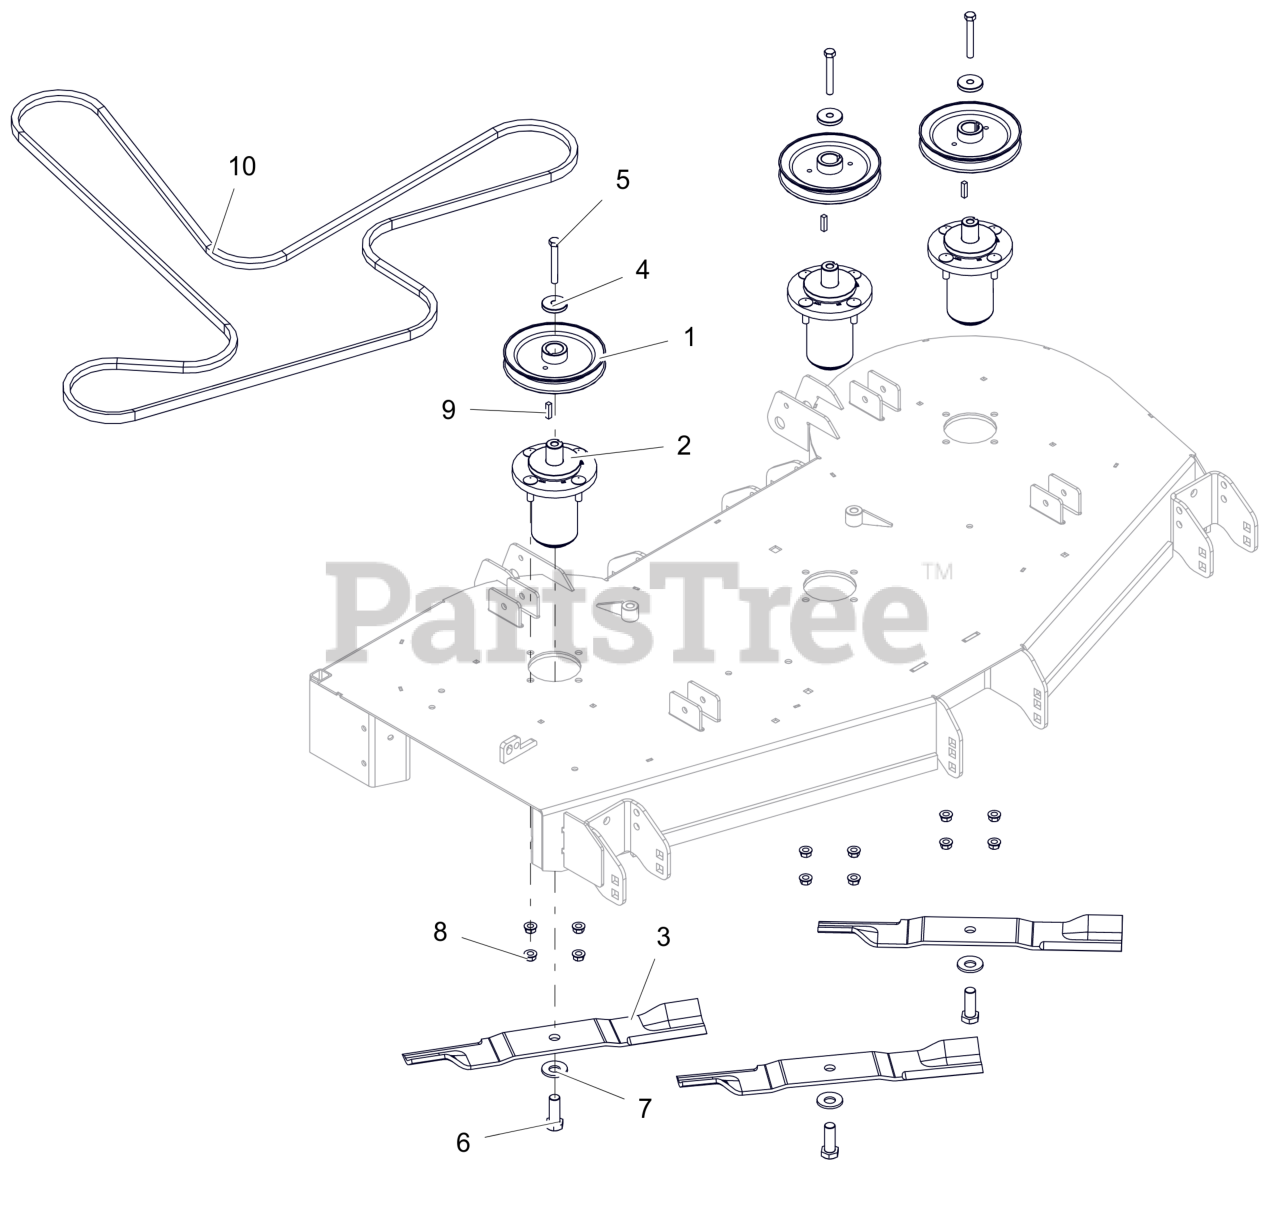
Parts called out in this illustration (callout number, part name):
1	PULLEY, V-1" ID X 6.00 OD
2	ASM, MAINT FREE ALUM SPINDLE
3	BLADE, 18.00" MOWER (HI-LIFT)
4	RETAINER, SHEAVE
5	BLT, HEX .38-16X2.75 G8 ZCC
6	BLT, HEX .62-18X1.75 G8 ZCC
7	WSHR-BLVL .669X1.535X.138
8	NUT-LK-CTR-FLG .375-16 GF ZCC
9	KEY, SQ .25X.25X1.00 RC 40-50
10	V-BELT, B RAW EDGE EPDM
